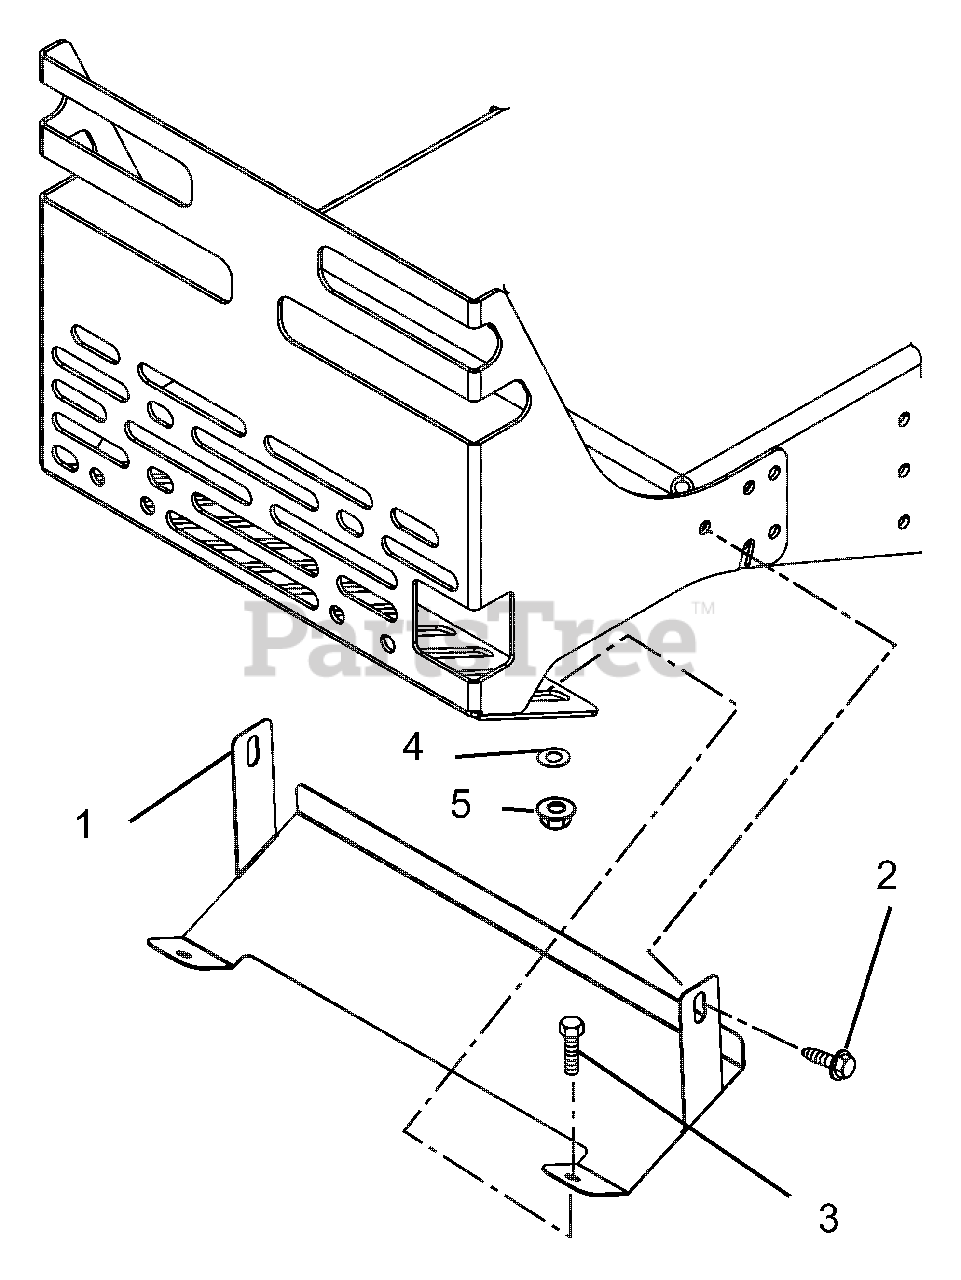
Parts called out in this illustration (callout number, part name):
1	SHIELD - HEAT - CZ
2	@SCR-TAP .38-16X.50 HWH TR YWZ
3	WMT, DECK IDLER PIVOT ARM
4	@WSHR-FL-STL.438X1.00X.083 YWZ
5	@NUT-LK-TOP-FLG .38-16 YWZC
